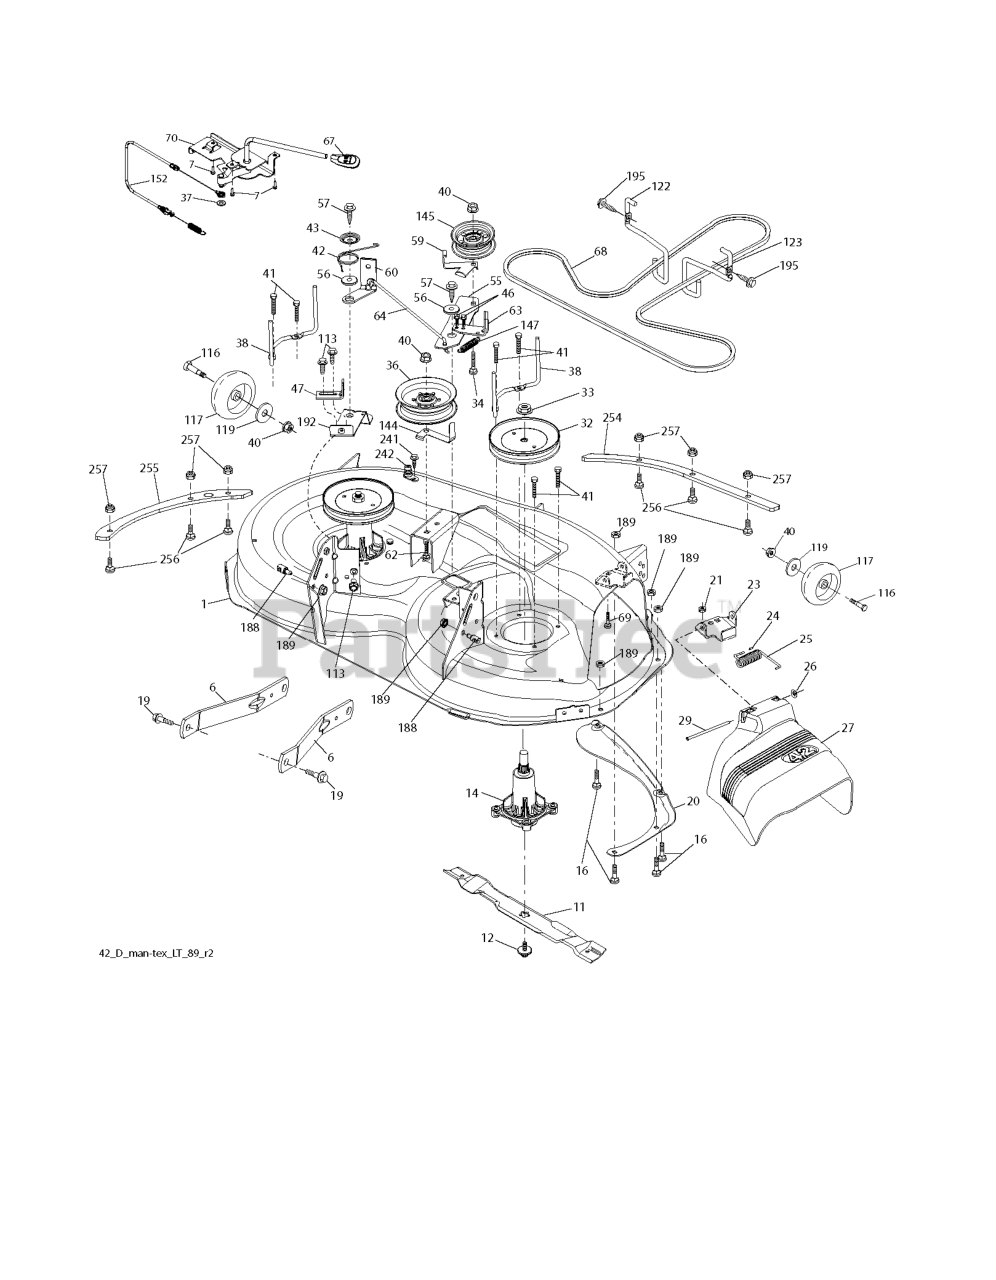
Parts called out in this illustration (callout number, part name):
1	REPAIR KIT KIT.SRV.WLDMENT.42
6	ARM.SUSPENSION.MOWER.R
11	42" HI-LIFT BLADE
12	SCREW.SEMS.7/16-20X1.HEX.HEAD
14	KIT.MANDREL.NONGREASE.TALL
16	BOLT ROUND HEAD SQUARE NECK BO
19	BOLT.SHOULDER
20	BAFFLE.VORTEX
23	BRKT.DEFLECTOR.38"2005+
24	CAP-SLEEVE LT
25	SPRING.TORSION.DEFLECT
26	NUT PUSH M
27	SHIELD.DEFLECTOR.MOWER.42"BLAC
32	PULLEY.MANDREL.5.438.PD
34	GSPW Bolts
36	PULLEY.IDLER.2006
37	WASHER PLAIN WASHER 3/8 X 0.08
38	KEEPER.BLT.PNT.MNDRL.PULL.6.25
40	NUT LOCK FLG 3/8-16 UNC
41	BOLT.HEX.WASHR.HED.313-18X1.19
42	SPRING.TORSION.BRAKE
43	SRPING.TORSION.RETAINE
46	SCREW.1/4-20X5/8
47	BRKT.CLUTCH.CABLE
55	IDLER.ARM.42"
56	SPACER.RETAINER
57	SCREW 3/8-16X1
59	GUARD, BELT
60	ARM BRAKE MOWER
63	ARM BRAKE MOWER
64	LINKAGE.BRAKE.ASM.ZINC
67	HANDLE.CLUTCH.CABLE.LT
70	CLUTCH.ASM.MANUAL.YT.PREDATORQ
113	BOLT.5/16HEX.WHS.HD
117	WHEEL.GAUGE.RALLY
122	KEEPER BELT ENGINE LH
123	KEEPER BELT RH
144	KEEPER.BELT.MOWER
145	PULLEY.IDLER.48"PRIMARY
147	RETURN SPRING
152	CABLE.MECHANICAL.CLUTCH
188	STUD.W/"D"ANTI-ROTATION
192	BRKT.BRAKE.STAND.LH.
195	SCREW, 3/8-16X3/4
241	SCREW.TT.#10-32X.5.3/8.FLANGE
242	PORT.WASHOUT
254	PLATES.RENFRC.42DECK.PT431FRNT
255	PLATES.RENFRCE.42DECK.X431SIDE
256	BOLT CUP HEAD SQUARE NECK 1/4-
257	NUT T
